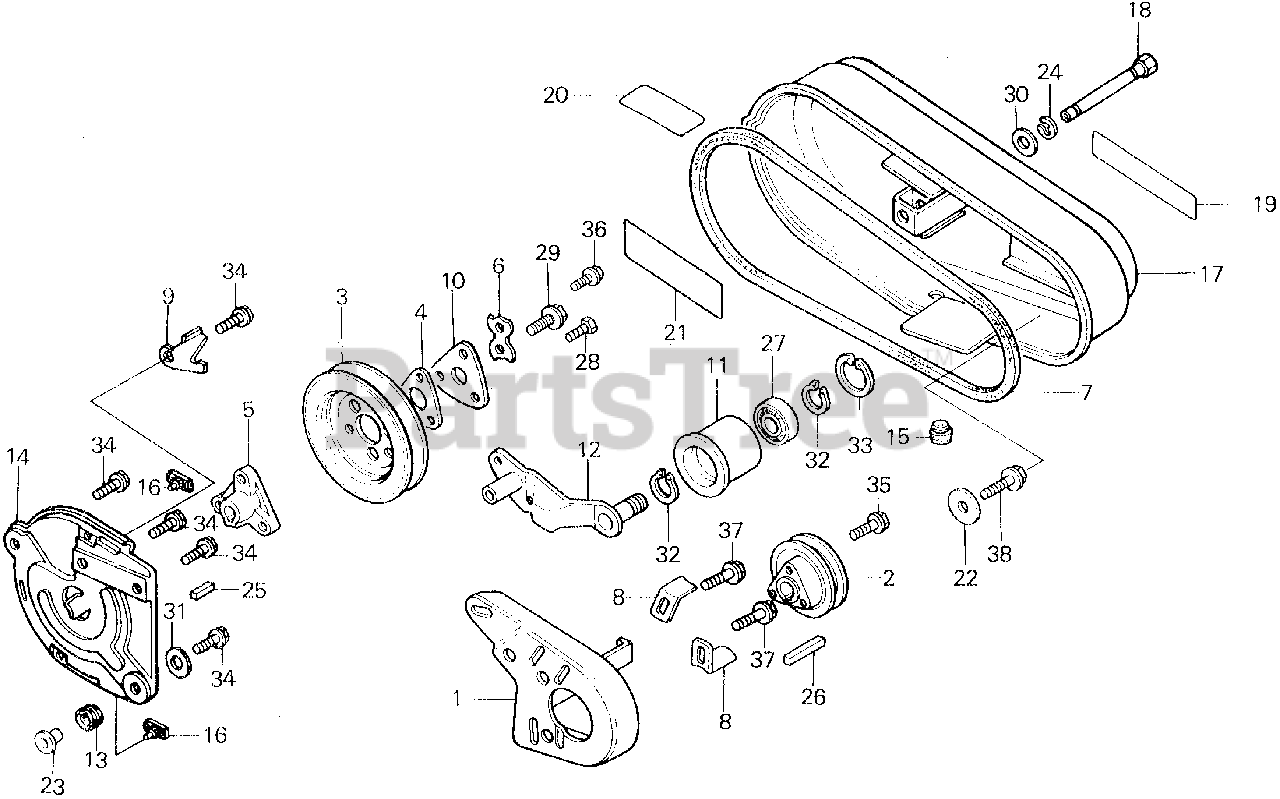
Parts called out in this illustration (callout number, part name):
1	PLATE, ENGINE ADJUSTING
2	PULLEY, DRIVEN (80MM)
3	PULLEY (125MM)
4	SPACER, PULLEY
5	BOSS, DRIVEN PULLEY (NOT AVAILABLE)
5	BOSS, DRIVEN PULLEY
6	WASHER, LOCK
7	V-BELT (SB-35)
7	V-BELT (35)
8	STOPPER E, BELT
9	STOPPER F, BELT
10	PLATE, PULLEY
11	ROLLER, TENSIONER
12	ARM, TENSIONER
13	GROMMET, WIRE HARNESS
14	STAY, BELT COVER
15	STOPPER, TENSIONER ARM
16	GROMMET, BELT COVER
17	COVER, BELT *NH31* (MCKINLEY WHITE)
17	COVER, BELT *NH31* (MCKINLEY WHITE) (NOT AVAILABLE)
18	LATCH, BELT COVER
19	MARK, BELT COVER
20	CAUTION, BELT COVER (ENGLISH)
21	CAUTION, BELT ADJUSTING (S)
22	WASHER (8MM)
23	WASHER, NUMBER BRACKET SETTING
24	E-RING (9MM)
25	KEY, FLAT (4X4X14)
26	KEY (5X5X33)
27	BEARING, RADIAL BALL (6202G)
29	BOLT, HEX. (8X16)
30	WASHER, PLAIN (10MM)
31	WASHER, PLAIN (8MM)
32	CIRCLIP (OUTER) (15MM)
33	CIRCLIP (INNER) (35MM) (NOT AVAILABLE)
34	BOLT, FLANGE (6X12)
36	BOLT, FLANGE (6X16)
37	BOLT, FLANGE (8X16)
38	BOLT, FLANGE (8X28)
